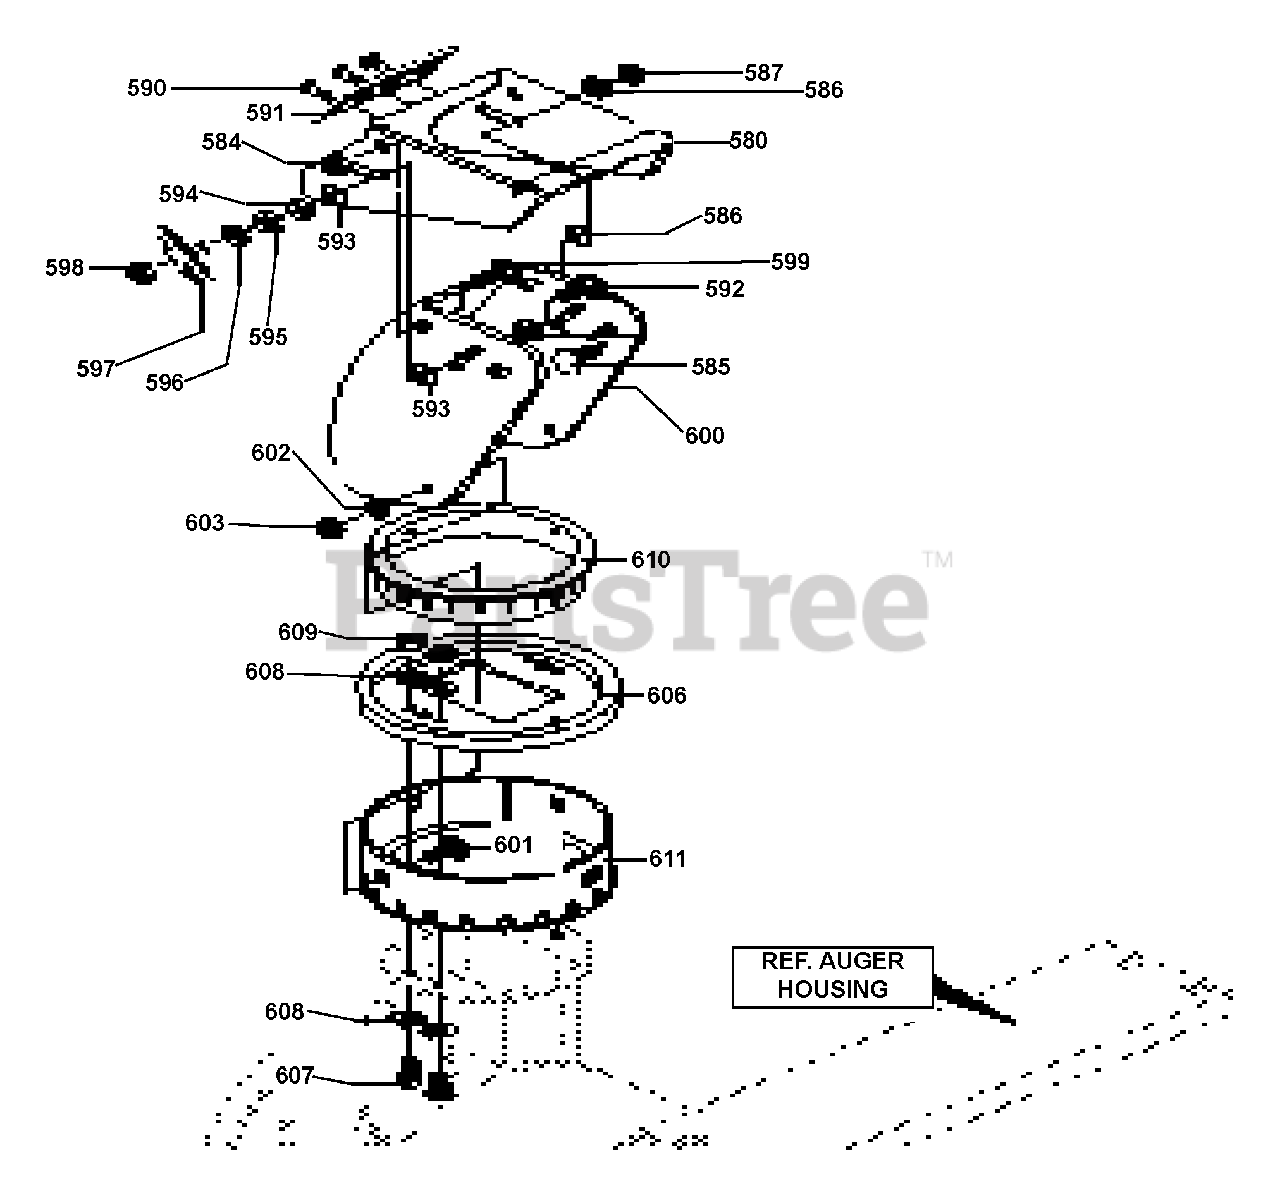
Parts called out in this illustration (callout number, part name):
580	CHUTE, UPPER
582	SCREW, 5/16-18X .75
584	NUT, 5/16-18
585	SCREW, 5/16-18X .75
586	WASHER, PLASTIC
587	NUT, 5/16-18
590	RIVET, POP
591	SKIRT, CHUTE EXT.
592	WASHER, PLASTIC
593	WASHER, PLASTIC
594	FLATWASHER .344X.69X.065
595	WASHER, SPLITLOCK
596	FLATWASHER .344X.69X.065
597	KNOB, T
598	NUT, 5/16-18 REGHEX
599	BOLT, 5/16-18X1.00
600	CHUTE, LOWER
601	BOLT, 5/16-18X1.00
602	FLATWASHER .344X .69X.065
603	NUT, 5/16-18
606	COLLAR, CHUTE
607	SCREW, 1/4-20X .75
608	FLATWASHER .281X .63X.065
609	NUT, 1/4-20 RGHXCTRLK
610	RETAINER, RING INNER
611	RETAINER, RING OUTER
